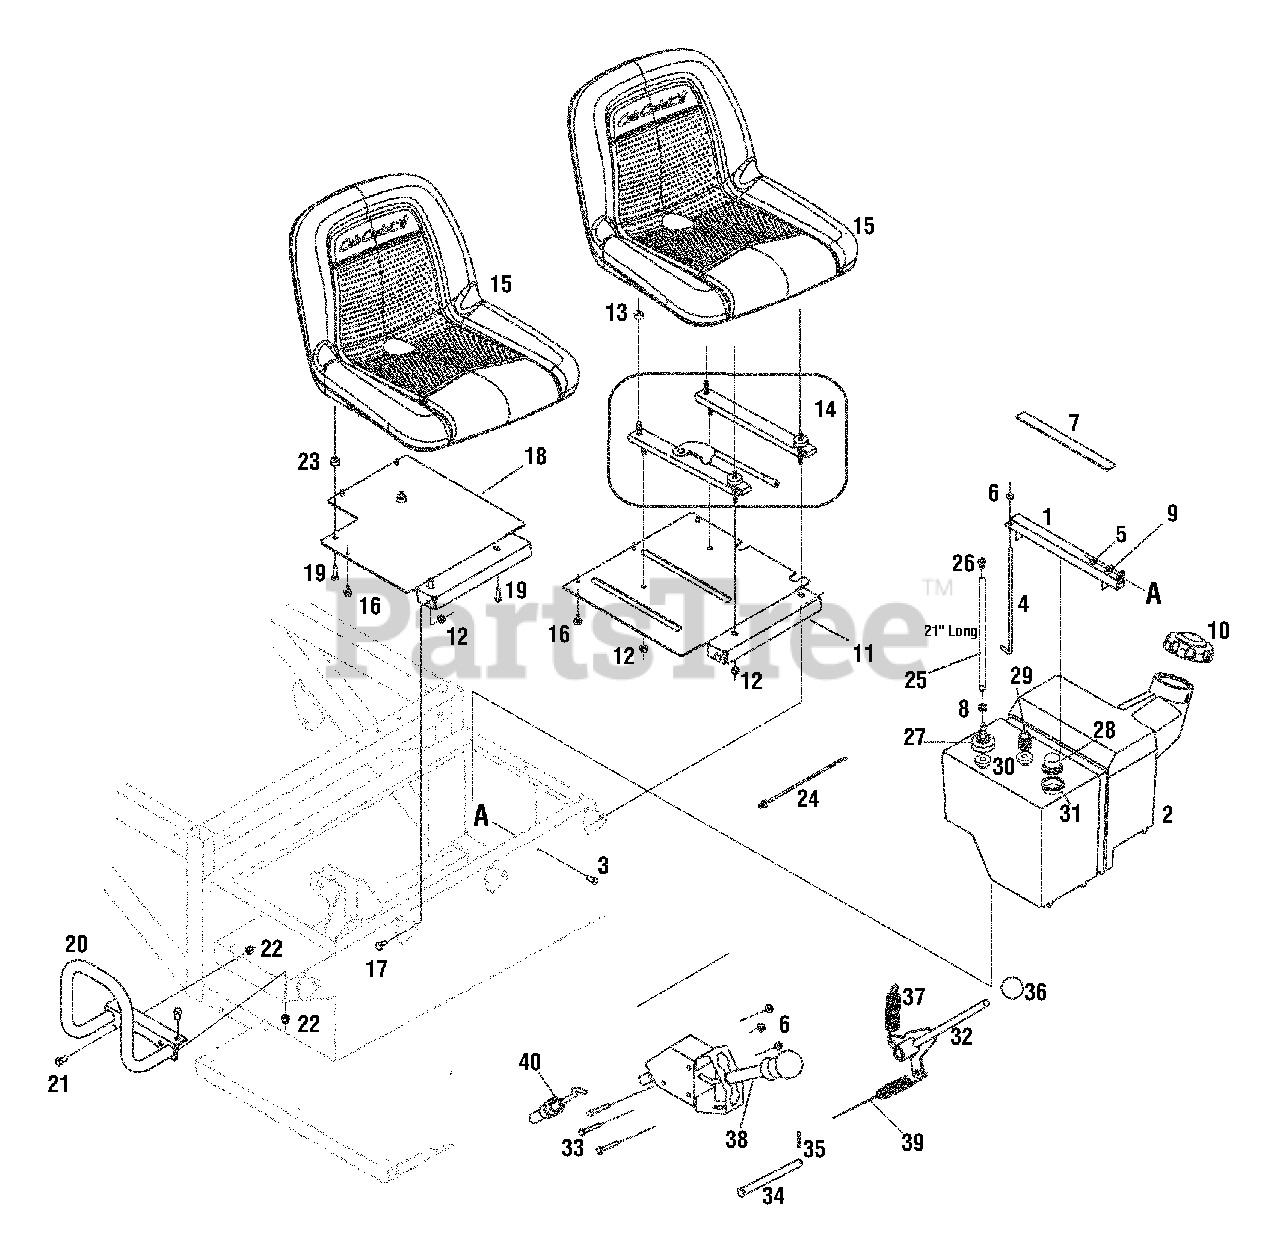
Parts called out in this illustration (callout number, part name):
1	Bracket Assembly, Fuel Tank
2	Tank Assembly, Fuel
3	Hex Screw, 5/16-18 x .75
4	Hold-down Rod, Fuel Tank
5	Sems Nut, 5/16-18
6	Nut, Flange Lock, 1/4-20
7	Gasket, Fuel Tank (11")
8	Clamp, Hose
9	Washer, .349 x .879 x .063
10	Cap, Fuel
11	Plate, Seat, LH
12	Nut, Flange Lock, 5/16-18, Gr5
13	Spacer, Seat
14	Track Assembly, Seat
16	Bumper
17	Shoulder Screw,.435 x.178-5/16 x.56
18	Plate, Seat, RH
19	Hex Screw, 5/16-18 x 1.0
22	Nut, Hex Lock Nylon, 3/8-16
23	Spacer,.315 x.750 x.375
24	Cable Tie
25	Fuel Line Hose
27	Fuel Return Fitting
28	Fuel Tank Gauge
29	Fuel Tank Shut Off Valve
30	Grommet
32	Diff Lock Shift Assembly
33	Hex Screw, 1/4-20 x 2.0
34	Clevis Pin
35	Cotter Pin
37	Extension Spring
38	Shifter Control
39	Diff Lock Control Cable
40	Shift Panel Control Cable
